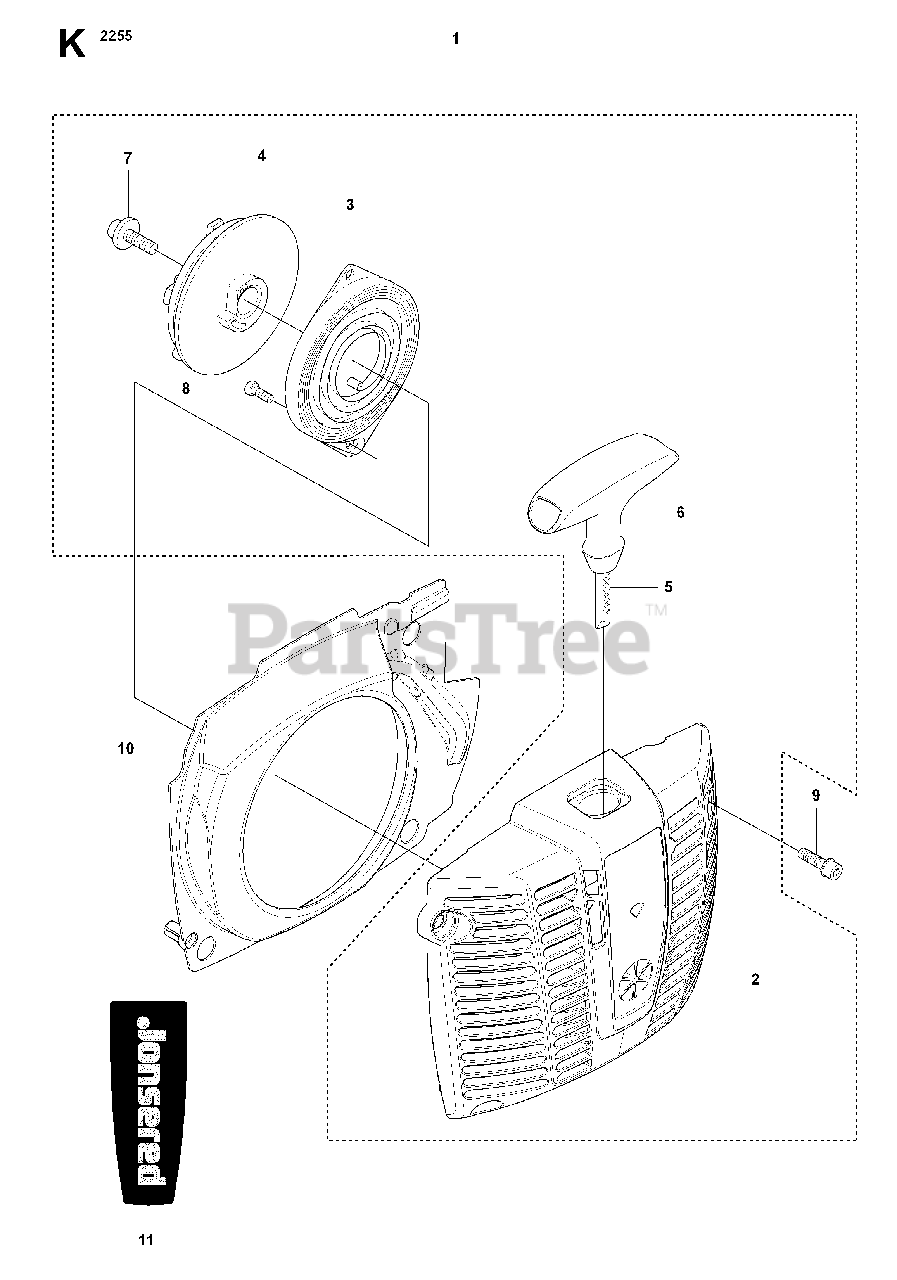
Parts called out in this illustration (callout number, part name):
3	RECOIL SPRING
4	STARTER PULLEY
5	STARTER ROPE
6	STARTER HANDLE
